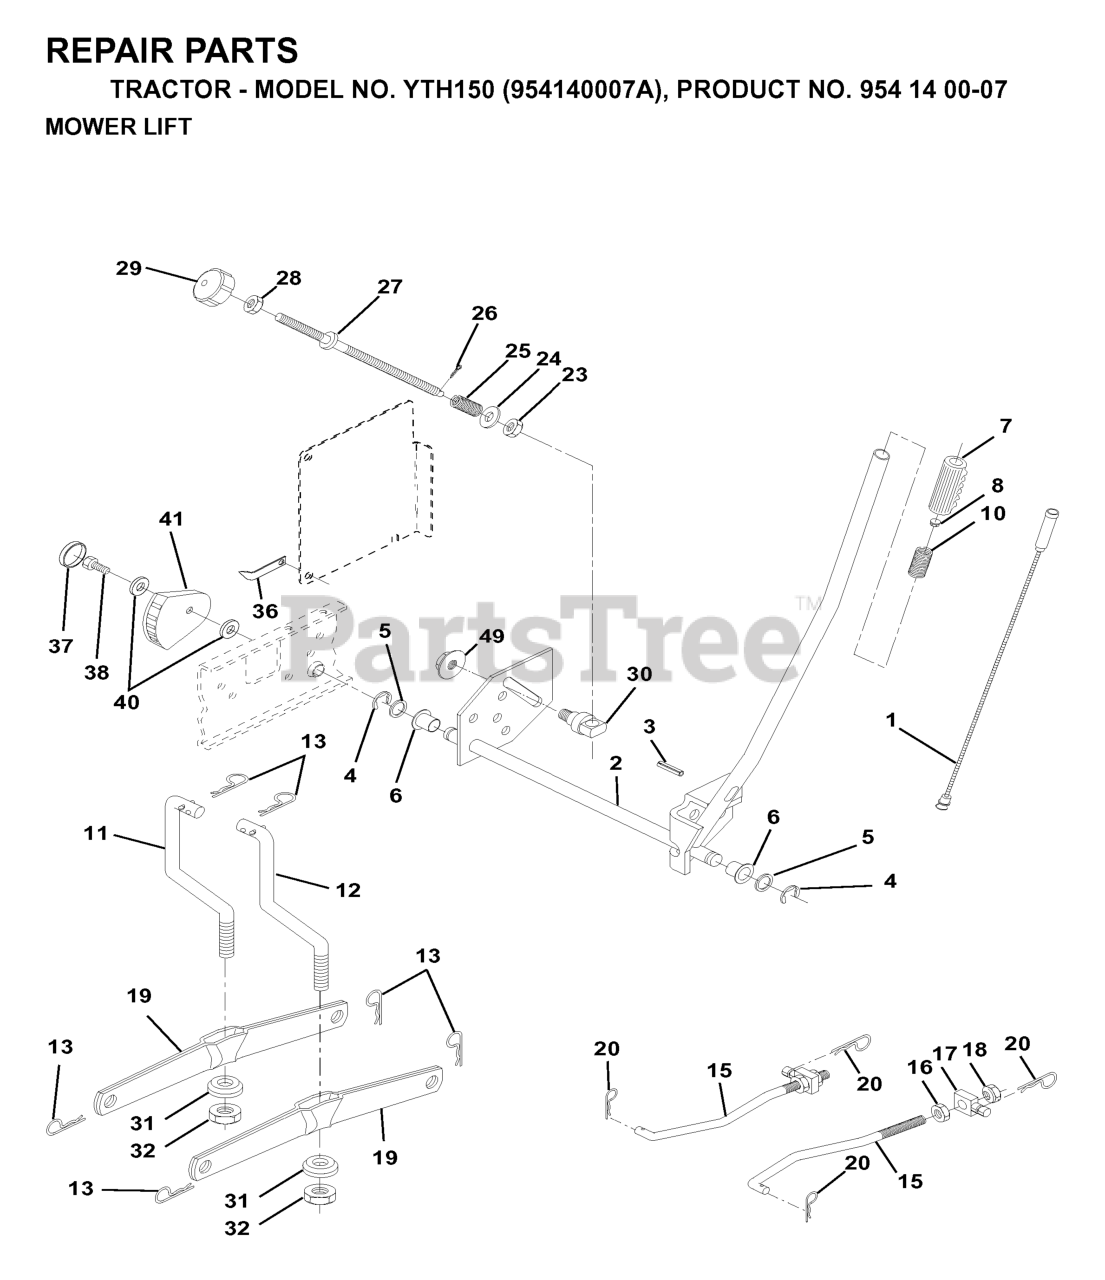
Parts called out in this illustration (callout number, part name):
1	WIRE.INNER.HANDLE.LIFT.LEVER
2	SHAFT ARM LIFT RH
3	PIN GROOVE.
4	RETAINING RING LT
6	BEARING.NYLON
7	GRIP HANDLE
8	PLUNGER BUT KIT
10	SPRING, COMP T
11	LINK LIFT LH
12	LINK LIFT RH
13	RETAINER-SPRNG RB
15	FRONT LINK
16	NUT.HEX.JAM.1/2-13
17	TRUNION
18	NUT.LK.W/WSH.1/2.
19	ARM.REAR.SUSPENSION
20	SPRING RETAINER
25	SPRING**
26	COTTER PIN
27	ROD ADJ LIFT
28	NUT
29	KNOB INF 3/8-16
31	BEARING PIVOT
32	NUT CROWNLOCK 3/8-24
36	POINTER, HEIGHT INDICATOR(2 2)
38	SCREW.THDROL.5/16-18X3/4.TTY
41	IND. HEIGHT STLT
49	NUT
